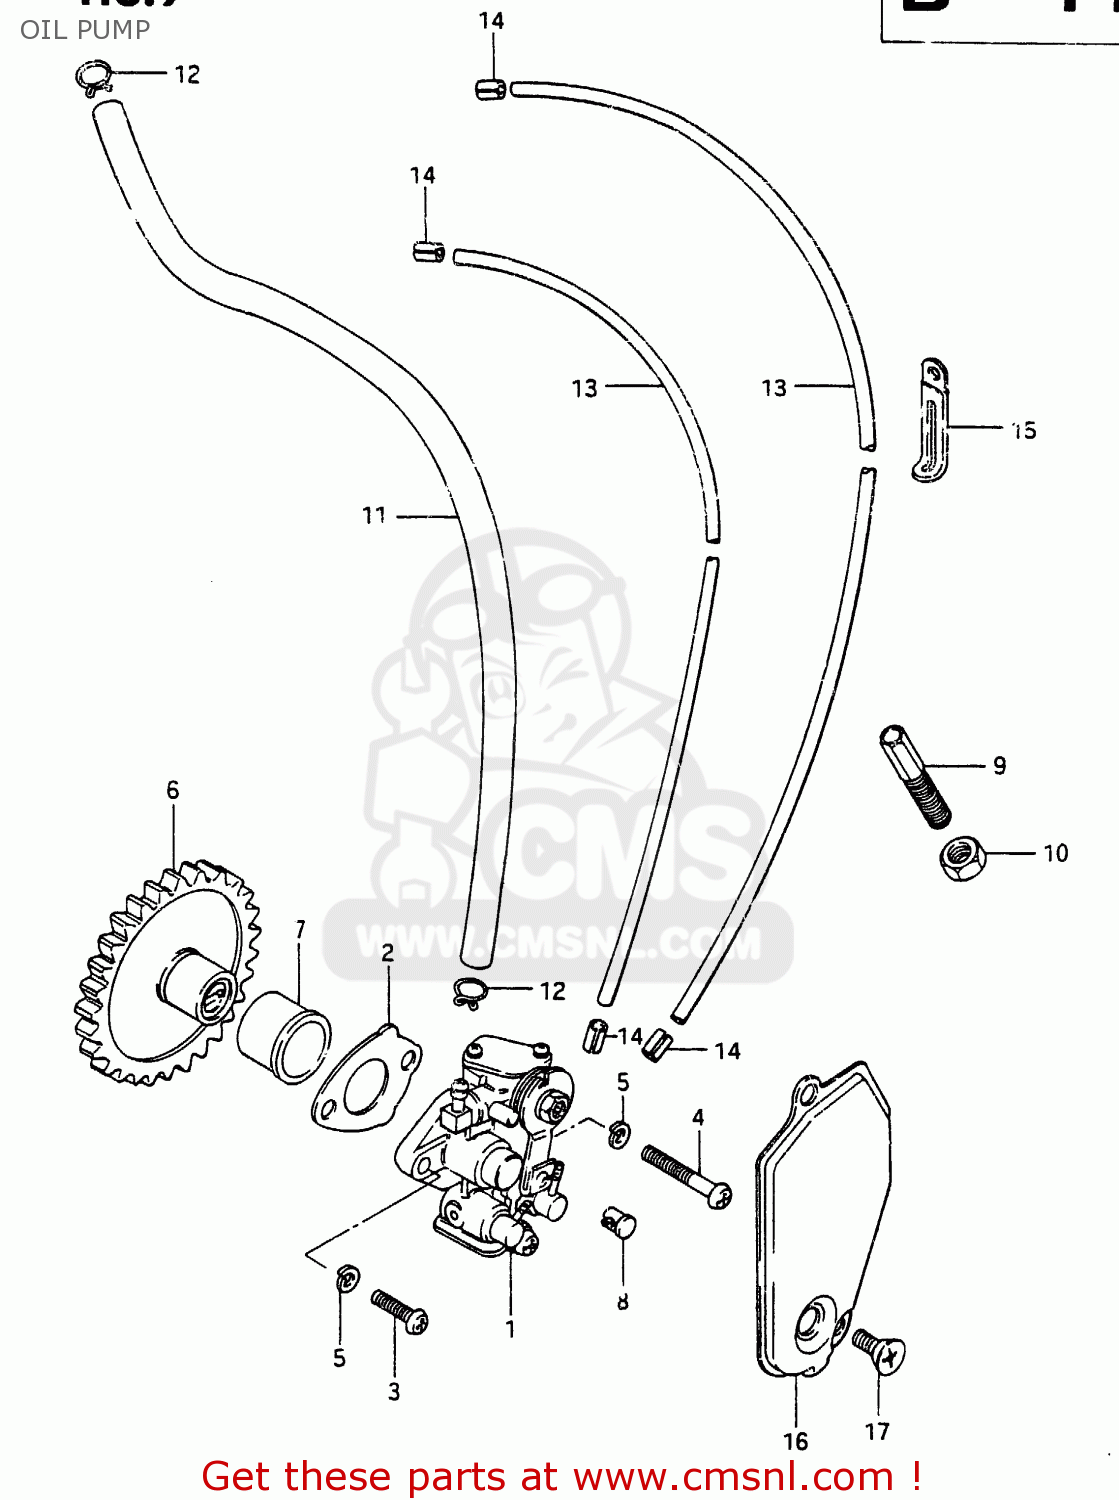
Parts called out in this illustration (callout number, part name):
1	PUMP ASSY,OIL
2	GASKET,OIL PUMP (NAS)
3	SCREW
4	SCREW
5	LOCK WASHER
6	GEAR, OIL PUMP DRIVE
7	BUSH
8	TERMINAL,CABLE
9	BOLT
10	NUT
11	HOSE
12	CLIP
13	HOSE
14	CLIP
15	CLAMP L:35
16	CAP, OIL PUMP INSPECTION
17	SCREW
